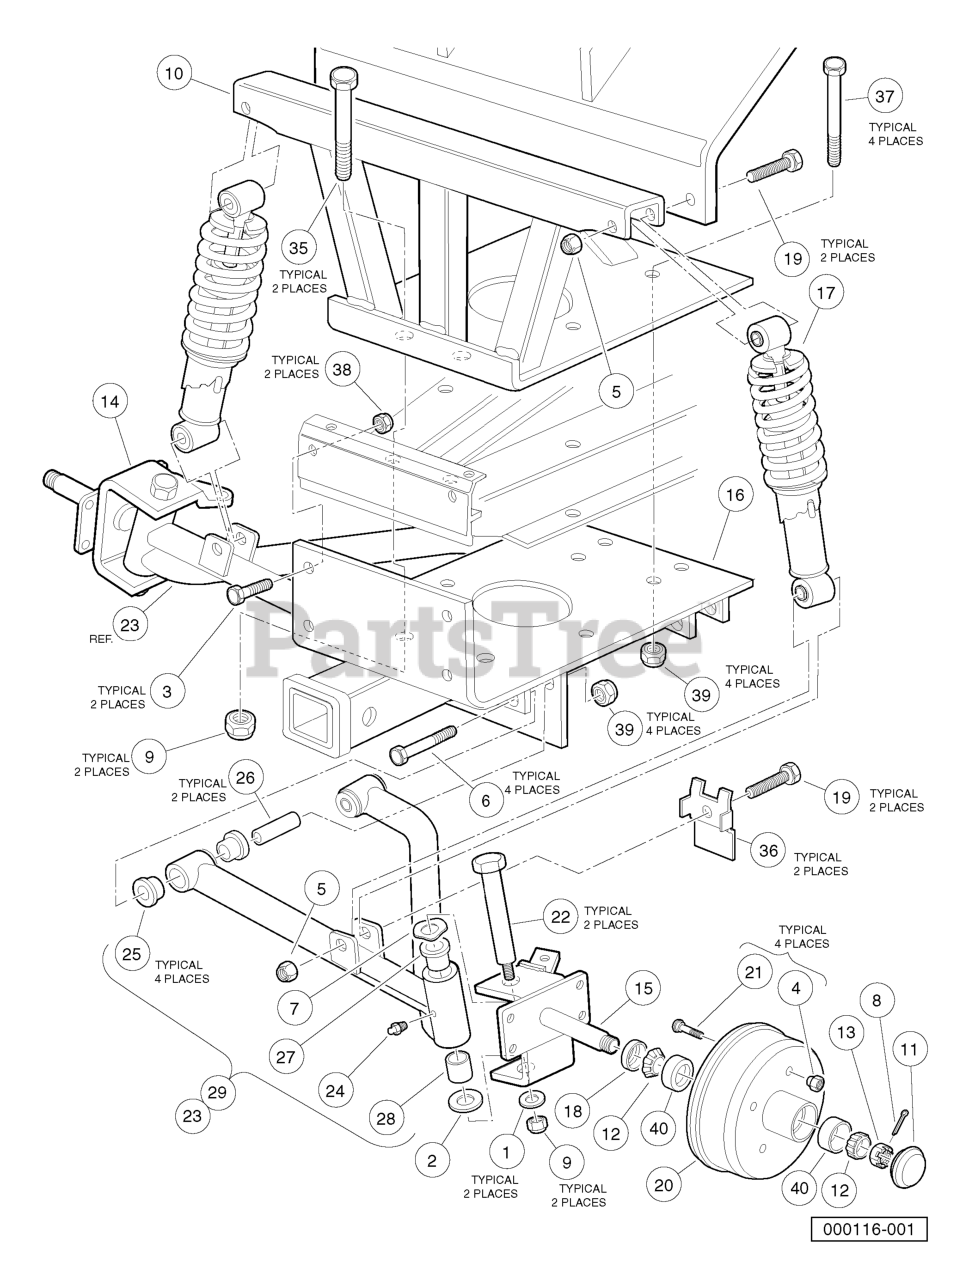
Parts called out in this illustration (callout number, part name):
1	WASHER, 1/2 TYPE A FLAT
2	BEARING THRUST
3	SCREW HEX CAP
4	NUT 1/2-20 LUG
6	SCREW, 3/8-16 X 2.75 HX HD CAP
7	WASHER, 1.125 OD WAVE
8	PIN-COTTER - .312 X 1.25"
9	LOCKNUT, 1/2-20 NYLON INSERT
10	SHOCK TOWER
11	DUST COVER
12	BEARING, TAPERED
13	NUT, 1.00-14 SLOTTED HEX JAM
14	ASM, SPINDLE - RH
15	ASM, SPINDLE - LH
16	SUSPENSION MEG PLATE
17	SHOCK ABSORBER, COIL OVER
18	SEAL, DOUBLE LIP
19	SCREW, 7/16-14 X 2.50 HEX CAP
20	FRONT HUB
22	KING PIN BOLT ASM
23	RIGHT A-ARM ASM
24	FITTING, 1/4-28 THRD FRM GREAS
25	BUSHING, URETHANE
26	A-ARM SLEEVE
27	BUSHING, FLANGED BROZE
28	BUSHING BRONZE SPINDLE
29	LEFT A-ARM ASM
30	FITTING, 1/4-28 THRD FRM GREAS
31	BUSHING, URETHANE
32	A-ARM SLEEVE
33	BUSHING, FLANGED BROZE
34	BUSHING BRONZE SPINDLE
35	SCREW, 1/2-20 X 5.0 HEX CAP
36	STEERING STOP MTG PLATE
37	BOLT, HEX HEAD
38	LOCKNUT, 5/16-18 NYLON INSERT
39	LOCKNUT, 3/8-16 HEX
